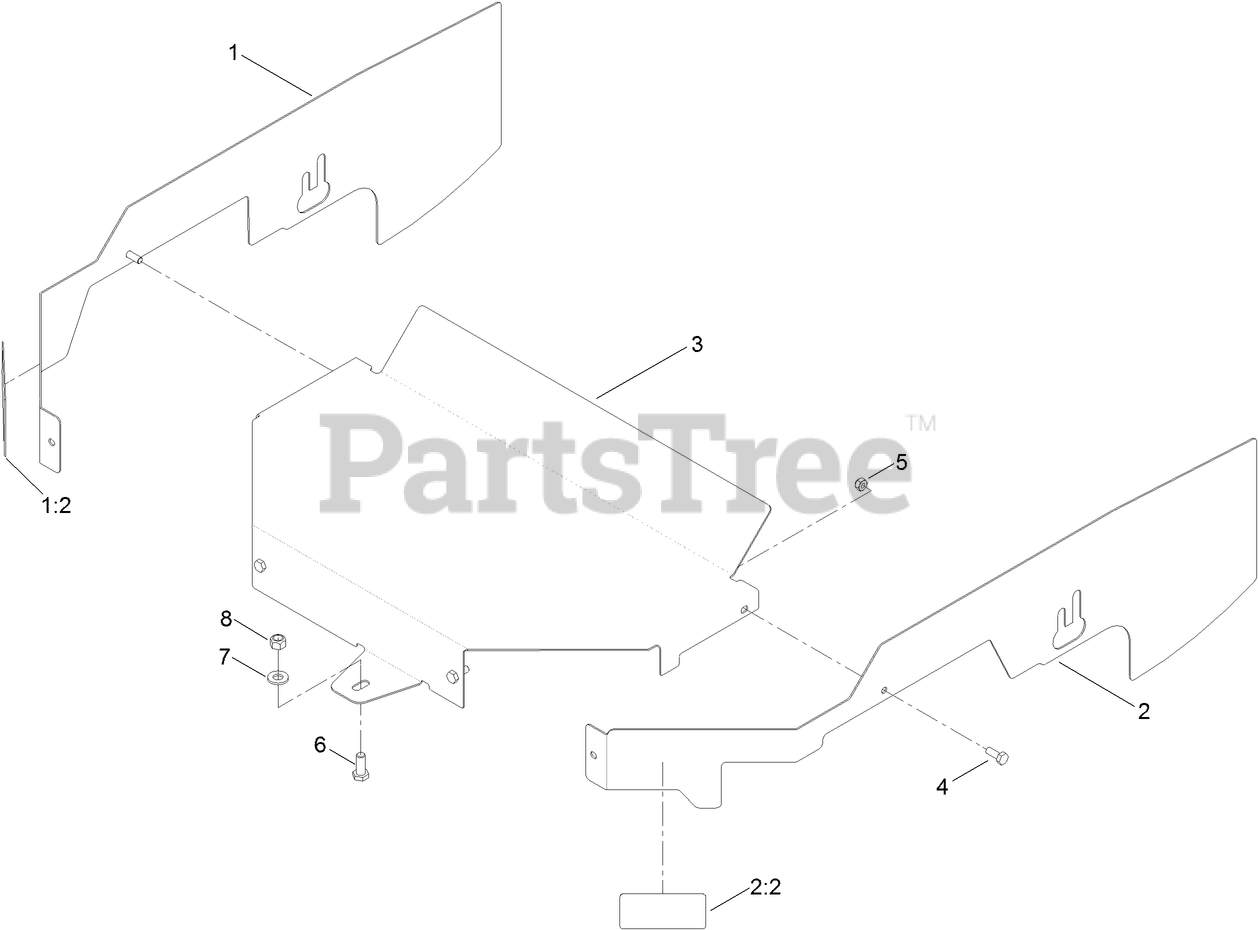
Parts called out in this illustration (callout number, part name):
1	GUARD-BELT, RH
1:2	DECAL-WARNING
2	GUARD-BELT, LH
2:2	DECAL-WARNING
3	GUARD-BELT, COVER
4	SCREW-HH
5	NUT-LOCK
6	SCREW-HH
7	WASHER-PLAIN
8	NUT-LOCK, NI
